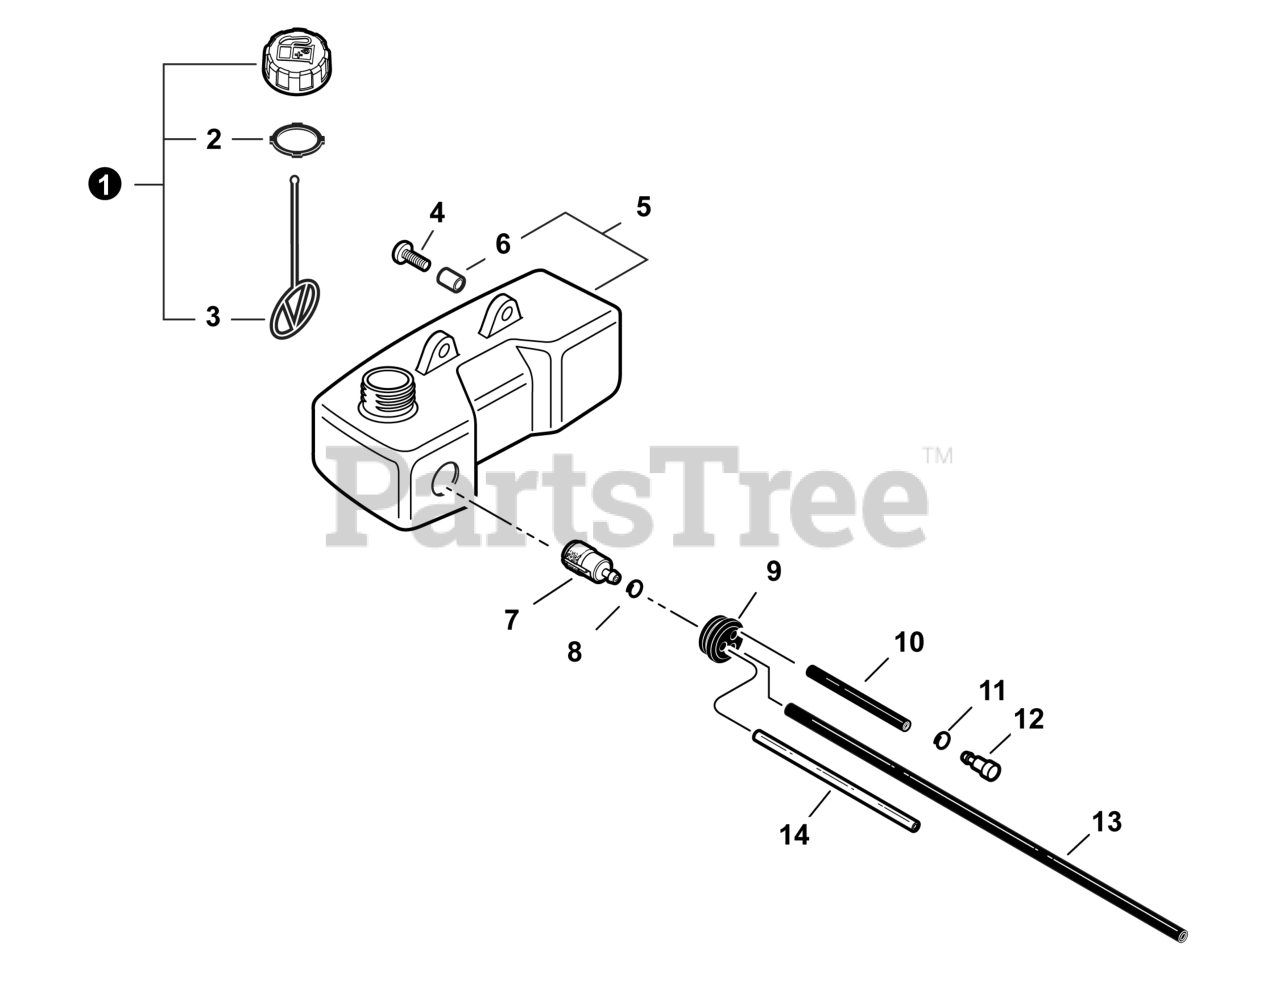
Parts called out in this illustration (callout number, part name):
1	CAP ASSY
2	GASKET, FUEL CAP
3	CONNECTOR, CAP L= 100 MM
4	SCREW 5x15
5	TANK ASSY, FUEL
6	SPACER 6.2x7.8x6
7	FILTER, FUEL
8	CLIP 6 MM
9	GROMMET, FUEL 5
10	PIPE, FUEL
11	CLIP 5.5
12	VENT ASSY
13	PIPE, FUEL 3x5x210 BLACK
14	PIPE, FUEL 3x6x50 YELLOW
